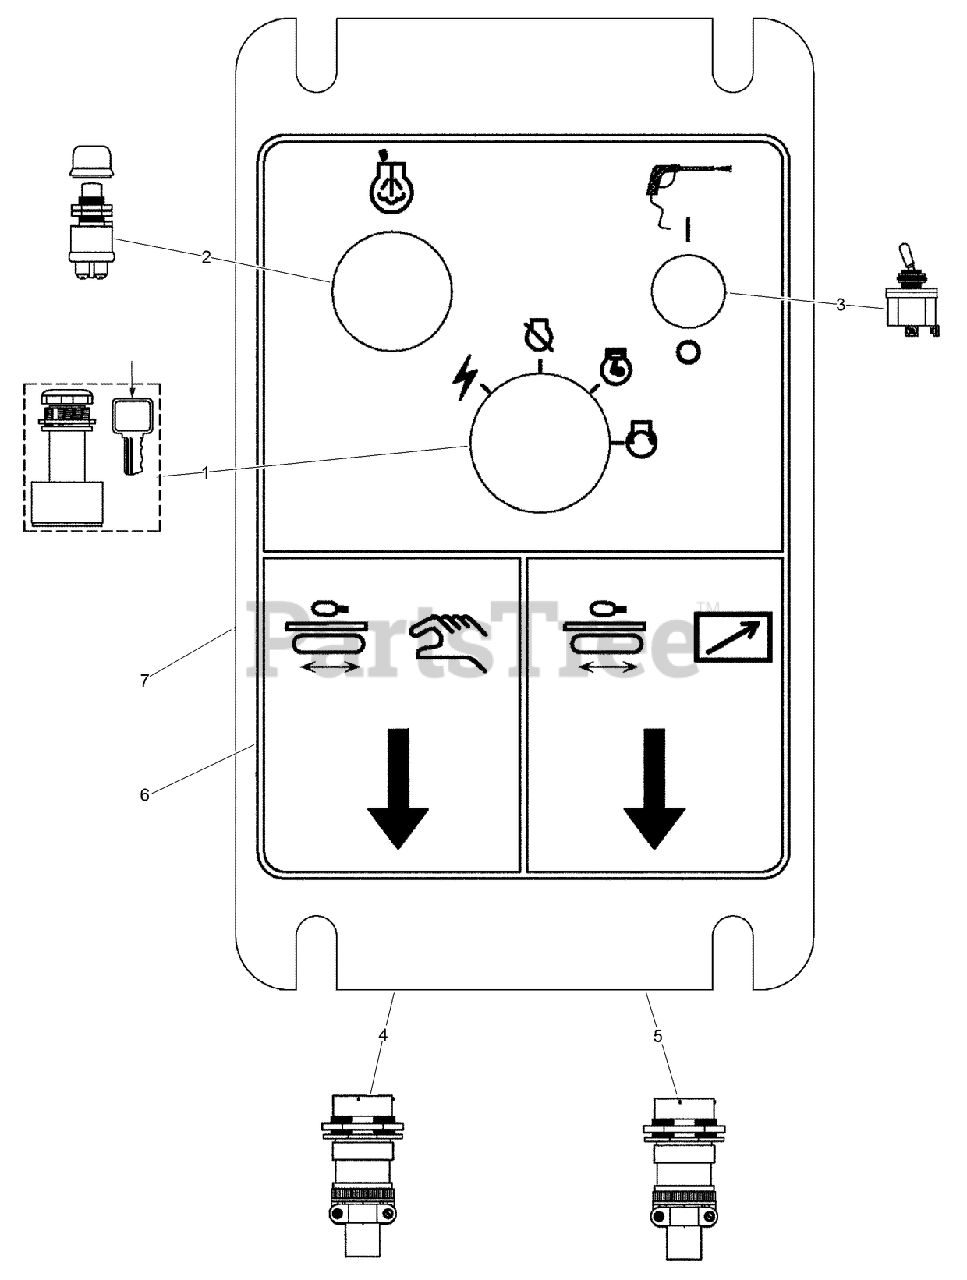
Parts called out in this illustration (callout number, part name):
1	SWITCH - Ignition, Keyed
2	SWITCH - Pushbutton, Ether
3	SWITCH-TOOGLE, SPST, ON-OFF (SEALED)
4	RECEPTACLE - Male, 18-14
5	RECEPTACLE - Male, 18-14
6	OVERLAY - Rear Controls
7	PLATE - Rear Controls Panel
